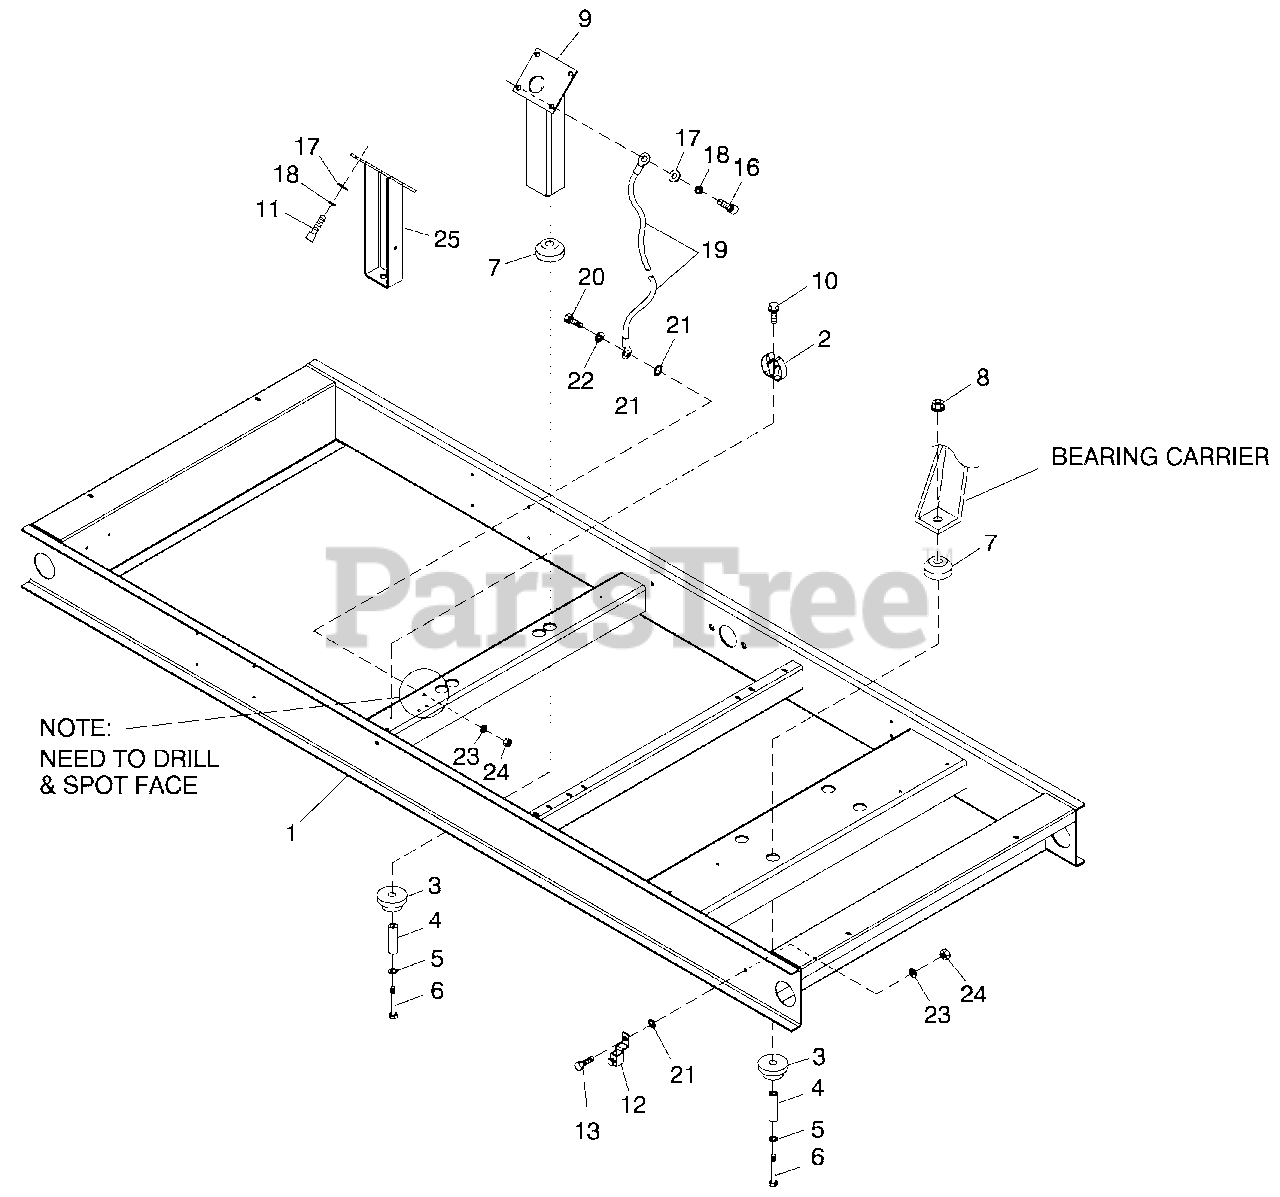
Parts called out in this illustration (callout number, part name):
1	BASE CP 6.8L70KW/5.4L 55KW DD
2	SPRING CLIP HOLDER .37-.62
3	DAMPENER VIBRATION
4	SPACER .49 X .62 X 1.87 PWDR/ZINC
5	WASHER FLAT M12
6	SCREW HHC M12-1.75 X 85 G8.8
7	DAMPENER VIBRATION 50 WHITE
8	NUT LOCKING M12-1.75
9	SUPPORT ENG 5.4L LH/RH 6.8L RH
10	SCREW HHTT M4-0.7 X 8 BP
11	SCREW SHC M10-1.5 X 30 G12.9 (5.4L)
12	LUG SOLDERLESS 3/0-#4 X 13/32 CU
13	SCREW HHC M8-1.25X 25 G8.8
16	SCREW SHC M10-1.5 X 30 G12.9
17	WASHER FLAT 3/8-M10 ZINC
18	WASHER LOCK M10
19	ASSY WIRE 14.00"
20	SCREW HHC M8-1.25X 30 G8.8
21	WASHER SHAKEPROOF INT 3/8
22	WASHER LOCK M8-5/16
23	WASHER FLAT 5/16-M8 ZINC
24	NUT HEX M8-1.25G8YEL CHR
25	SUPPORT, ENGINE (6.8L LH SIDE)
